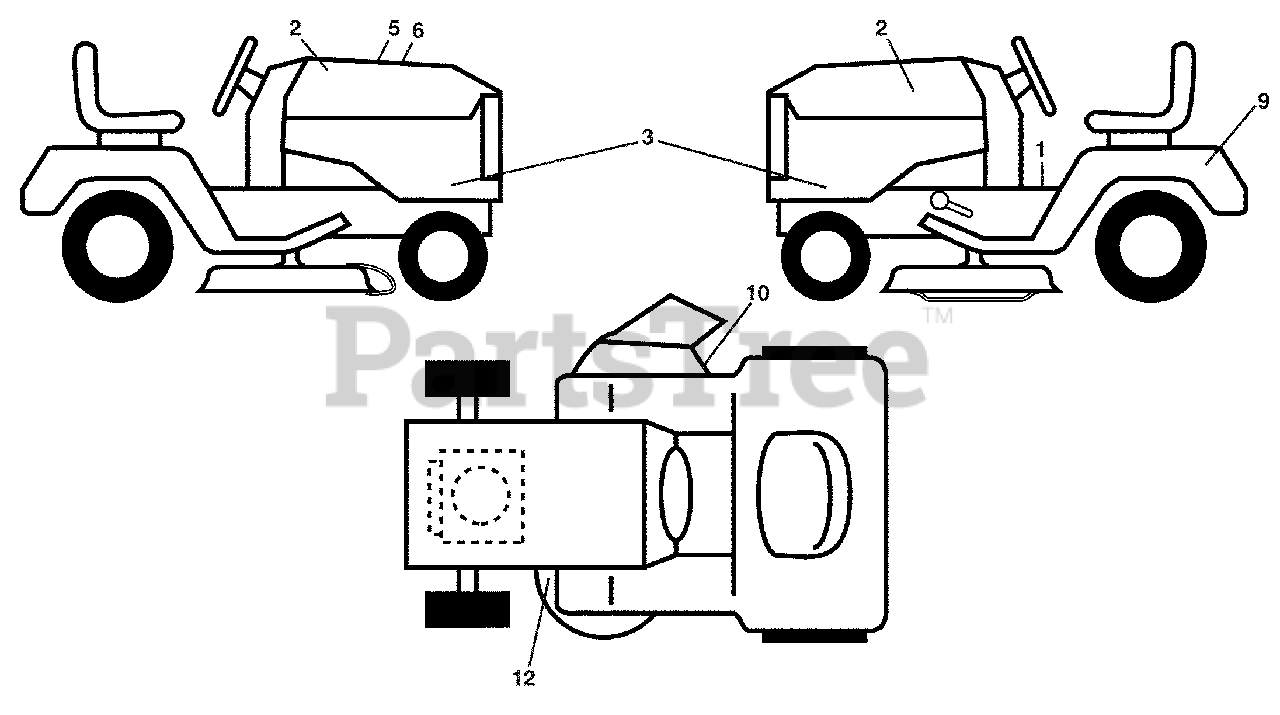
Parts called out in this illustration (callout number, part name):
1	Decal, Warning
2	Decal, Hood
3	Decal, Hood Panel SD
5	Decal, Customer Respons.
6	Decal, Replacement
9	Decal, Battery Dnge/Poi
10	Decal, Warning
12	Decal, Mower V-Belt Schematic
